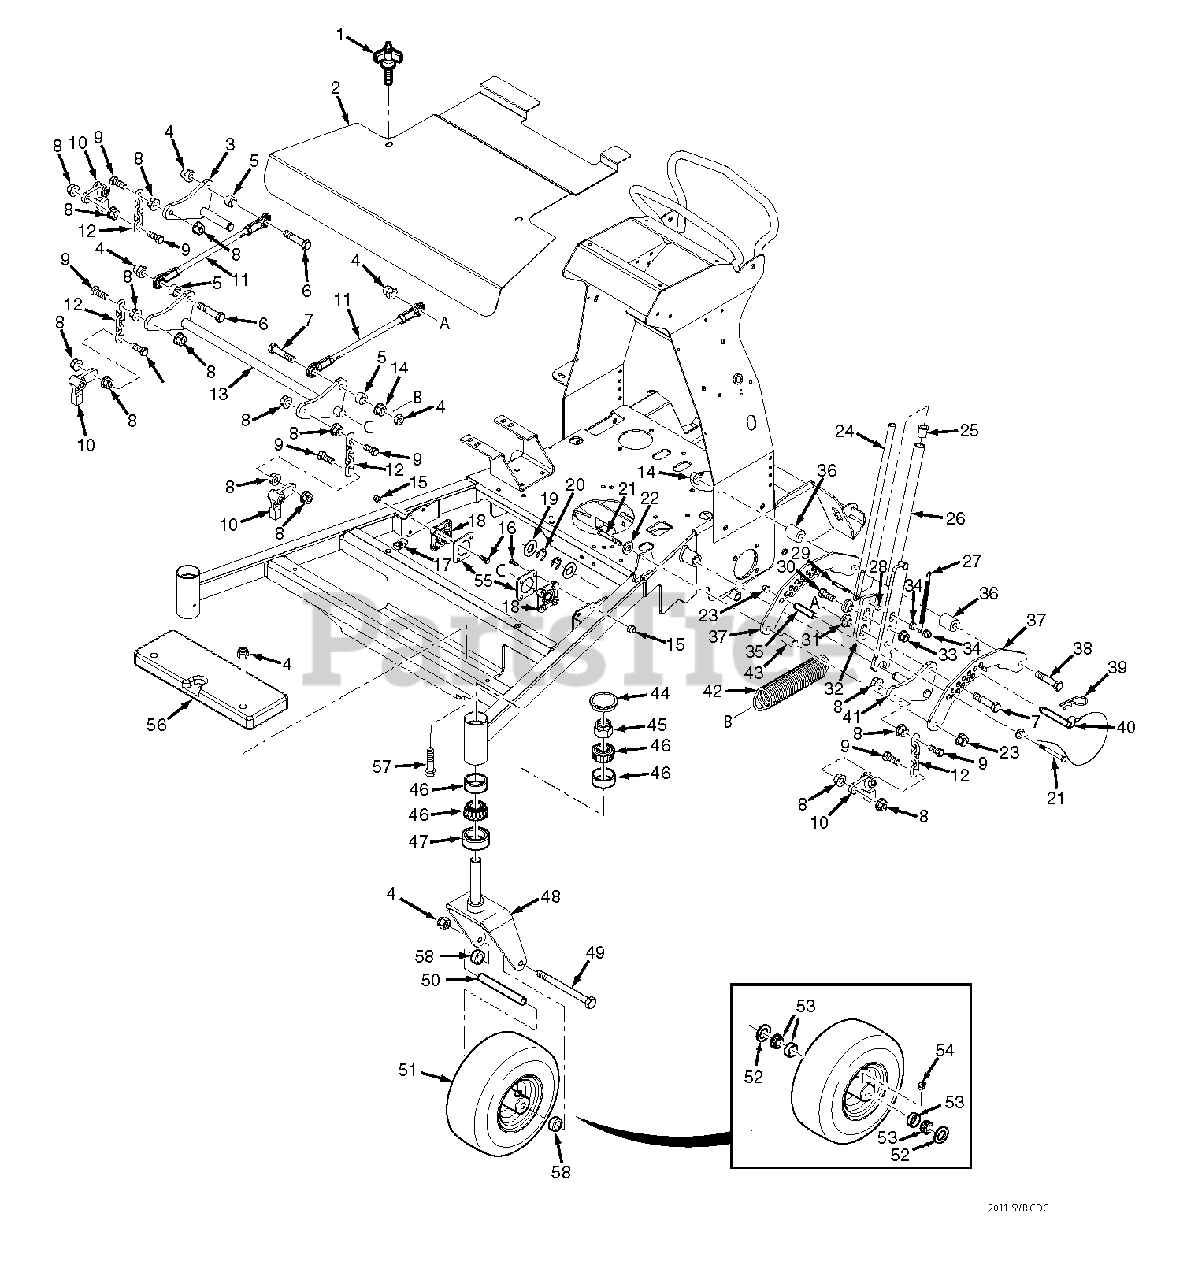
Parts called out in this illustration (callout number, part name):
1	Knob w/Stud
2	Belt Cover w/Decals (36A)
2	Belt Cover w/Decals (48V & 52V)
3	Arm Weldment, RH
4	Nut, Elastic Stop 1/2-13
5	Spacer
6	Bolt, Hex Head 1/2-13 x 2-1/2"
7	Bolt, Hex Head 1/2-13 x 3"
8	Nut, Serrated Flange 3/8-16
9	Bolt, Hex Head 3/8-16 x 1-1/2"
10	Lever, Deck Level
11	Linkage, Deck Lift (36A)
11	Linkage, Deck Lift (48V & 52V)
12	Chain
13	Deck Lift Weldment (36A)
13	Deck Lift Weldment (48V & 52V)
14	Nut, Serrated Flange 1/2-13
15	Nut, Elastic Stop 5/16-18
16	Bolt, Hex Head 5/16-18 x 1"
17	U-Nut, 3/8-16
18	Bearing, Deck Lift - 36A
18	Bearing, Deck Lift - 48V & 52V
19	Flatwasher, 3/4-.766 x 1.25 x .0598
20	Retaining Ring, .750 "E"
21	Bolt, Hex Head 3/8-16 x 3"
22	Flatwasher, 3/8-.391 x .938 x .105
23	Nut, Elastic Stop 3/8-16
24	Actuator Rod
25	Bearing
26	Handle Weldment, Deck Latch
27	Spring, Deck Latch
28	Spacer
29	Bolt, Hex Head 3/8-16 x 2-1/2"
30	Bolt, Hex Head 1/2-13 x 1-3/4"
31	Bushing, Deck Latch
32	Deck Latch, Outer
33	Nut, Serrated Flange 1/2-13
34	Nut, Elastic Stop 3/8-16
35	Spacer
36	Spacer (36)
36	Spacer (48 / 52)
37	Bracket, Deck Height
38	Bolt, Hex Head 1/2-13 x 4-1/2"
39	Hair Pin Cotter
40	Pin Assembly w/Lanyard
41	Arm Weldment, LH
42	Spring, Deck Lift
43	Spacer
44	Cap, Grease
45	Nut, Elastic Stop 1"-14
46	Bearing w/Race
47	Seal, 2" OD x 1.625 ID
48	Caster Yoke Weldment
49	Bolt, Hex Head 1/2-13 x 6-1/2"
50	Sleeve, Caster Wheel
51	Caster Wheel Assembly, 11 x 4.0-5
53	Bearing, Tapered Roller
54	Grease Fitting, 45 Degree
55	Reinforcement, Bearing - 48V & 52V
56	Weight
57	Bolt, Hex Head 1/2-13 x 2-3/4"
57	Bolt, Hex Head 1/2-13 x 4-1/2" (36A - Two Weights)
57	Bolt, Hex Head 1/2-13 x 5-1/2" (Three Weights Installed)
58	Spacer, Caster Wheel
